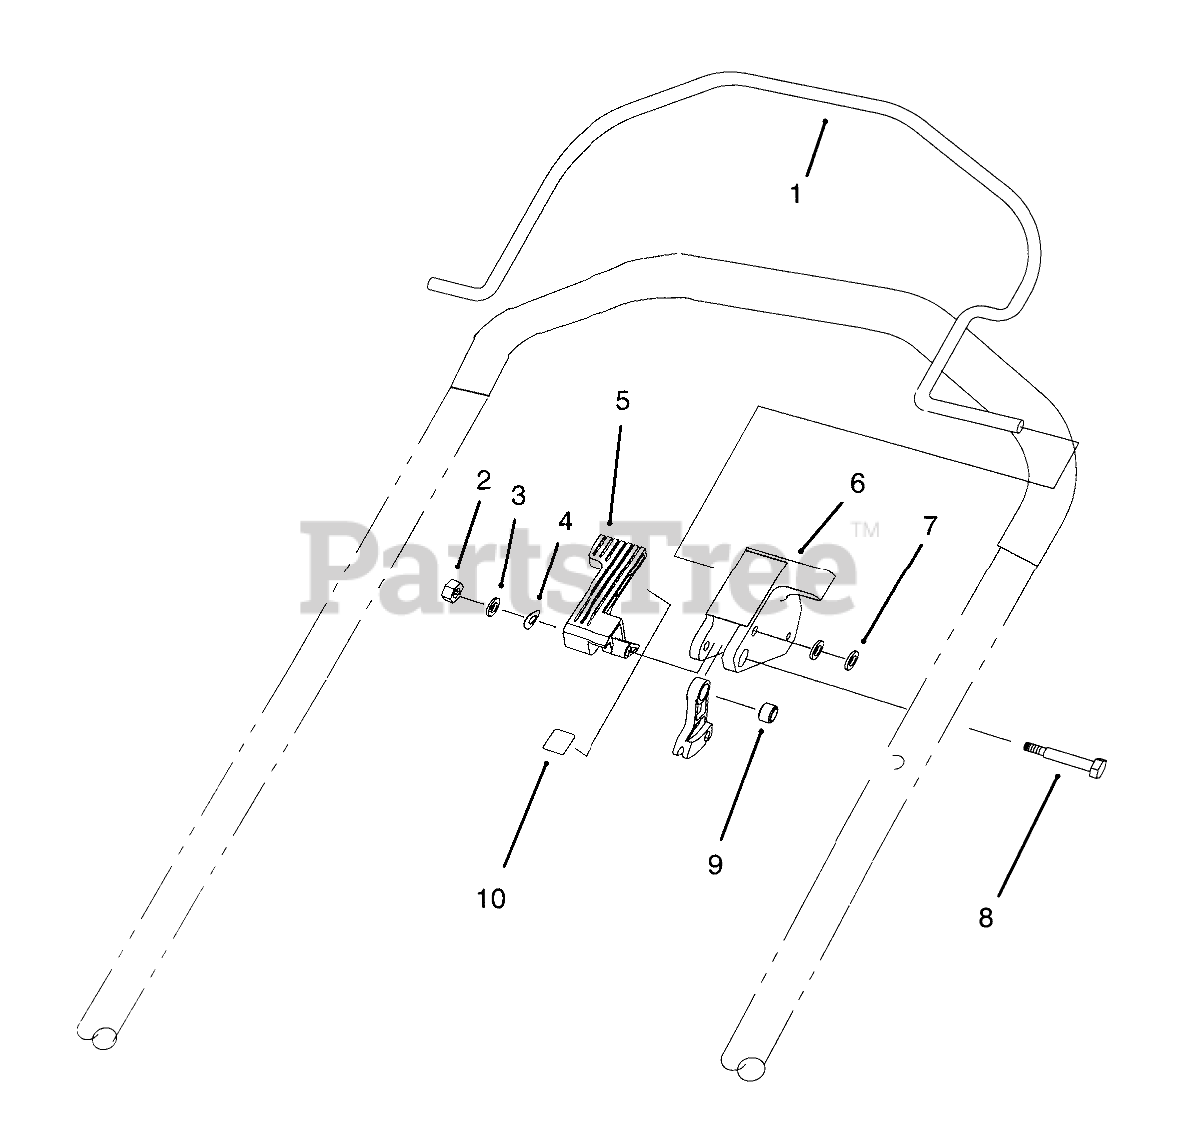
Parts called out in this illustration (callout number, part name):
1	BAIL - CONTROL
2	NUT-LOCK, NI
3	WASHER-PLAIN
4	WASHER - SPRING
5	LEVER - SHIFT
6	STOP - PIVOT, PLASTIC
7	WASHER-FLAT
8	SHOULDER BOLT
9	SPACER-LEVER, TRACTION
10	DECAL - TRACTION
